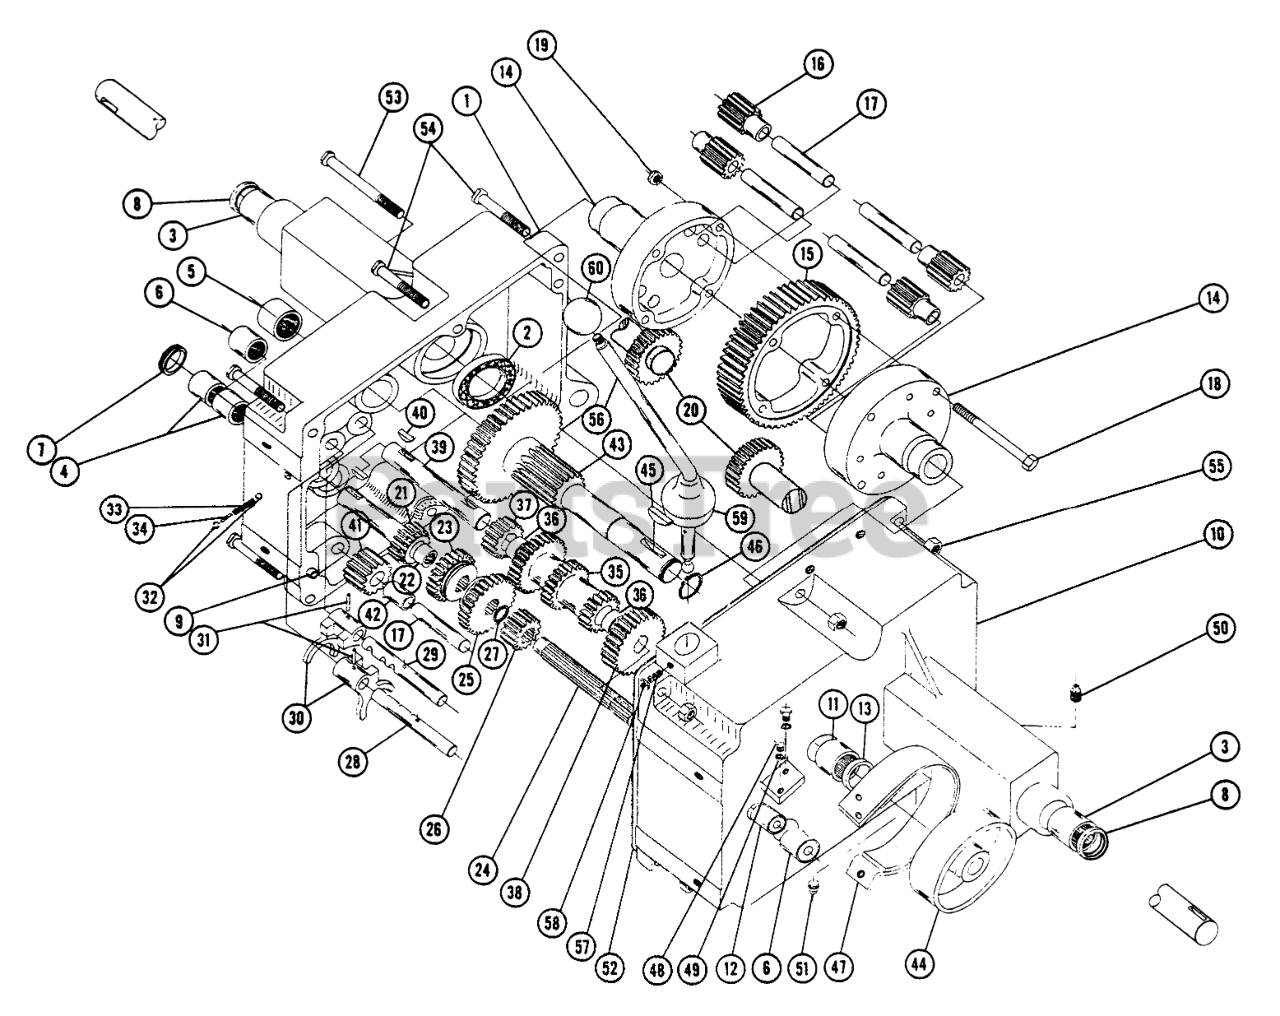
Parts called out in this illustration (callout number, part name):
5	BEARING-NEEDLE
6	BEARING-NEEDLE
9	PIN-DOWEL
14	DIFFERENTIAL CASE
15	Gear-Differential Bull
17	PIN-DIFFERENTIAL
22	BEARING-NEEDLE
28	RAIL-SHIFT
29	RAIL-REAR SHIFT
30	FORK-SHIFT
31	PIN-ROLL
32	BALL-DETENT
34	PIN-SHIFT
36	BUSHING-BRONZE
40	Key
41	GEAR/BUSHING ASM-REVERSE IDLER
42	BUSHING
45	KEY-WOODRUFF
48	Bolt-1/4-20 x 5/8
50	Plug 1/4 Pipe
51	Plug 3/8 Pipe
52	GASKET-TRANSMISSION
53	Bolt Hex 3/8-16 x 1
54	Bolt, 3/8 16 x 2
56	Stick-Ship Ass-y.
57	SETSCREW
58	Nut 1/4-20
59	COVER-DUST
